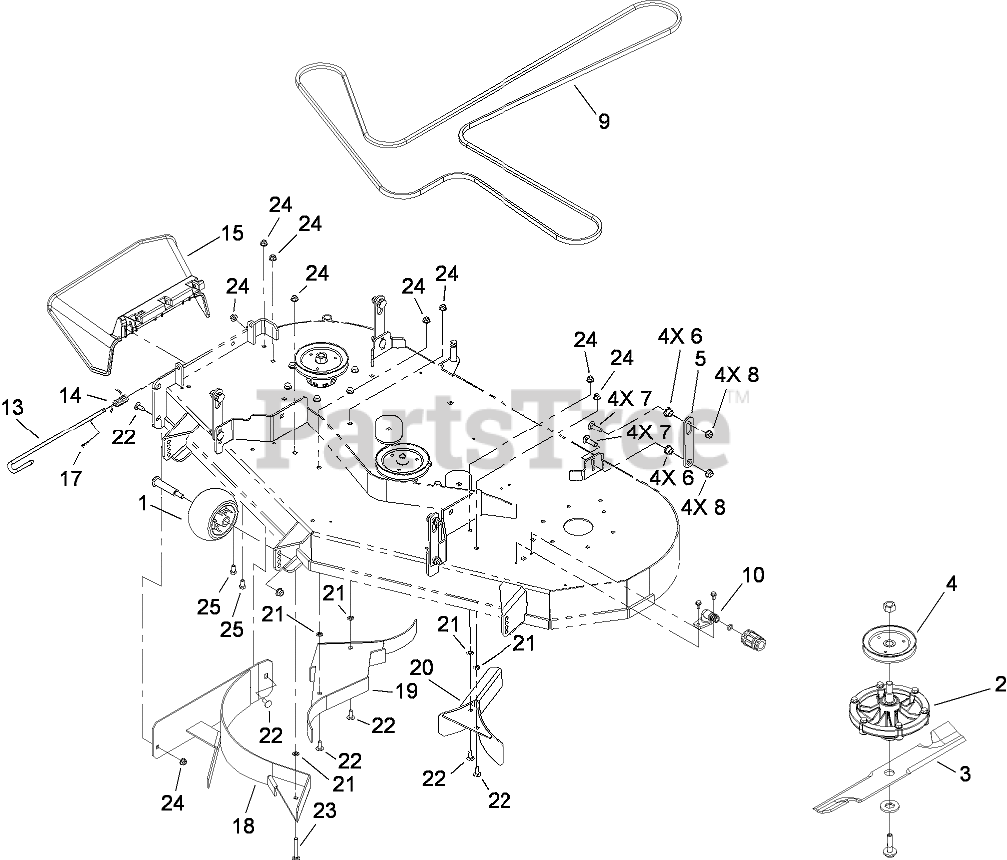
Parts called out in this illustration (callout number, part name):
1	ANTI-SCALP ROLLER KIT
2	COMPLETE CUTTER HOUSING ASM
3	BLADE-MULCH
4	PULLEY-DECK
5	HANGER-DECK
6	BUSHING-FLANGED
7	BOLT-CARR
8	NUT-HF, NI
9	BELT
10	WASHOUT PORT KIT
13	PIN-CHUTE
14	SPRING-TORSION
15	CHUTE-DISCHARGE
17	PIN-COTTER
18	RH MULCH BAFFLE ASM
19	CENTER BAFFLE ASM
20	LH MULCH BAFFLE ASM
21	RING-RETAINING, BOLT
22	SCREW-CARR
23	BOLT-CARR
24	NUT-HF, NI
25	SCREW-HH
